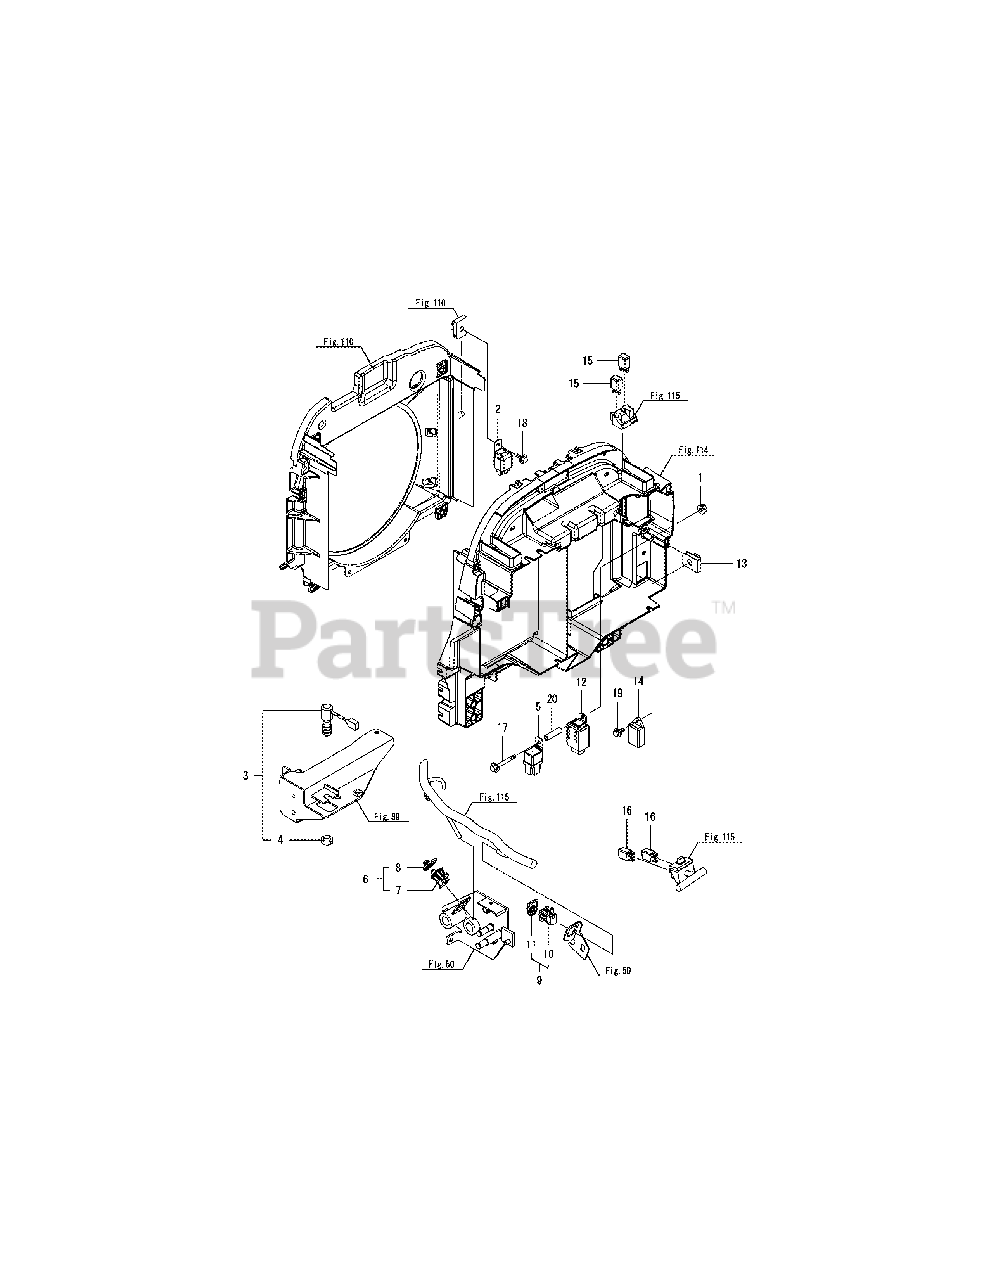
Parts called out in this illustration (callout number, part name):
1	Nut W/Washer 6
2	Relay, Starter
3	Switch, Brake Lamp
4	Lock Nut M12 Plated
6	Switch Nc Assy, Pedal
7	Switch Nc, Pedal
8	Protective Cover
9	Switch, Seat, Delta, As
10	Switch, Seat, Delta, As
11	Protective Cover
15	Relay(Acm13211M01
16	Relay(Acm13211M01
17	Bolt M 6X 50 Plated
18	Bolt M 6X 16 Plated
19	Bolt M 6X 16 Plated
